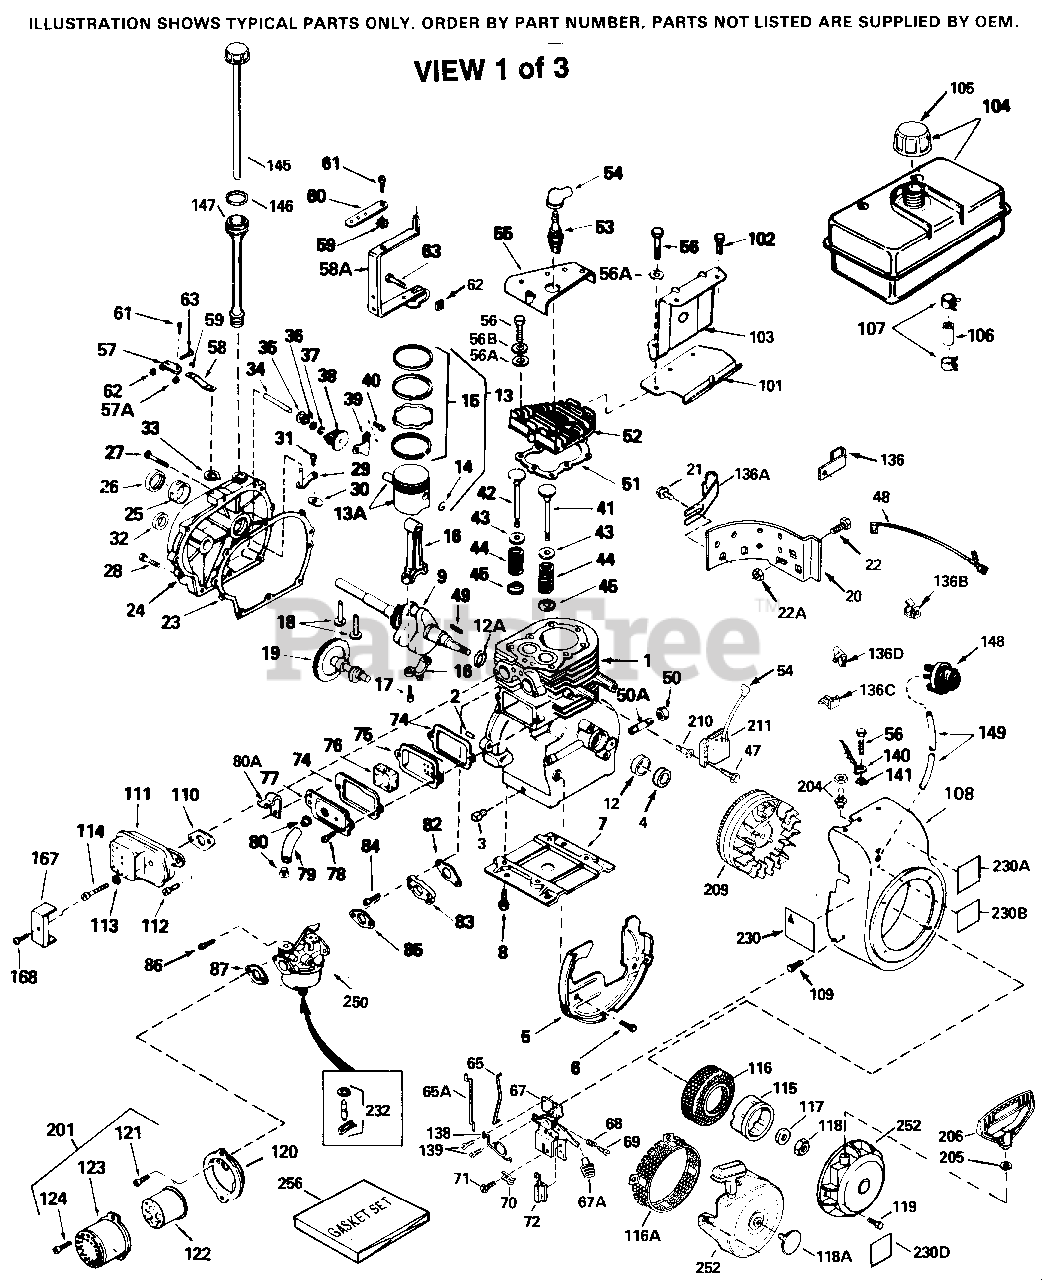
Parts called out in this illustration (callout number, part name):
1	"Cylinder (Incl. 2, 20 & 72)
2	Dowel Pin
15	Governor Rod (Incl. 15A & 15B)
15A	Governor Yoke
15B	Screw, 6-40 x 5/16"
16	Governor Lever
17	Governor Lever Clamp
18	Screw, 8-32 x 5/16"
19	Speed Control Spring
20	Oil Seal
23	Ball Bearing
25	Blower Housing Baffle
26	Screw, 1/4-20 x 5/8"
28	Lock Nut, 8-32
30	Crankshaft
35	Screw, 10-32 x 3/4"
36	Lock Washer #8
37	Lock Nut, 10-32
38	Retaining Ring
40	Piston, Pin & Ring Set (Std.)
40	Piston, Pin & Ring Set (.010" OS)
40	Piston, Pin & Ring Set (.020" OS)
41	Piston & Pin Ass'y. (Std.) (Incl. 43)
41	Piston & Pin Ass'y. (.010" OS) Incl. 43
41	Piston & Pin Ass'y. (.020" OS) Incl. 43
42	Ring Set (Std.)
42	Ring Set (.010" OS)
42	Ring Set (.020" OS)
43	Piston Pin Retaining Ring
45	Connecting Rod Ass'y. (Incl. 46)
48	Valve Lifter
50	Camshaft (BCR)
60	Blower Housing Extension
62	Screw, 8-32 x 3/8
65	Screw, 10-24 x 1/2"
69	* Cylinder Cover Gasket
70	Cylinder Cover Incl. 74,75,80,175 & 1 76
72	Oil Drain Plug (Sq. hd., 1/4-18)
74	Bearing Retainer
75	Oil Seal
80	Governor Shaft
82	Governor Gear Ass'y. (Incl. 81)
83	Governor Spool
84	Retaining Ring
86	Screw, 1/4-20 x 1-1/4"
87	Screw, 1/4-20 x 1-3/4"
101	Spark Plug Cover
102	Solid State Mounting Stud
103	Screw, Torx T-15, 10-24 x 1"
110	Ground Wire
119	* Cylinder Head Gasket
120	Cylinder Head (Incl. 3 of 130)
125	Exhaust Valve (Std.)(Incl. 151)
125	Exhaust Valve (1/32" OS) (Incl. 151)
126	Intake Valve (Std.) (Incl. 151)
126	Intake Valve (1/32" OS) (Incl. 151)
139	Governor Gear Bracket
140	Screw, 10-24 x 1/2"
149	Valve Spring Cap
150	Valve Spring
173A	Breather Tube Grommet
184	* Carburetor To Intake Pipe Gasket
186	Governor Link
200	Control Bracket (Incl. 19, 203 & 204)
203	Compression Spring
204	Screw, 5-40 x 7/16"
206	Terminal
209	Screw, 10-32 x 1/2"
210	Conduit Clip
211	Screw, 10-32 x 3/8"
224	* Intake Pipe Gasket
227	Air Cleaner Elbow (Machined)
228	Stud, 1/4-20 x 6.20"
229	Nut & Lock Washer, 1/4-20
232	Pop Rivet (Purchase Locally)
235	Air Cleaner Elbow Fitting
238	Screw, 10-32 x 7/8"
239	* Air Cleaner Gasket
239A	* Air Cleaner Gasket
245A	Air Filter
250	Air Cleaner Cover
260	Blower Housing
262	Screw, T-40, 5/16-24 x 21/32"
265	Cylinder Head Cover
272	Screw, 5/16-18 x 3/4"
273	Carburetor Flange
275	Muffler
285	Starter Cup
286	Starter Screen
287	Screw, 1/4-28 x 7/16"
291	Fuel Line
292	Fuel Line Clamp
298	Screw, 1/4-15 x 3/4"
299	"U" Type Nut
300	Fuel Tank (Incl. 292 & 301)
301	Fuel Cap (Red)
305	"O" Ring
305	Oil Fill Tube
308	Fill Tube Clip
310	Oil Fill Plug
325	Wire Clip
340	Fuel Tank Bracket
341	Fuel Tank Bracket
342	Screw, 1/4-20 x 5/8"
366	Muffler Elbow
366A	Muffler Nipple
367	Lock Nut
370	Instruction Decal
370A	Logo Decal
370B	Instruction Decal
380	Carburetor (Incl. 184)
390	Rewind Starter
400	* Gasket Set (Incl. items marked PK in notes) Incl. part #'s 27272 (2), 2789 6 (2), 27913 (1), 27915 (2), 27930 (1 ), 28938B (1), 29673 (1), 30684 (1), 31688 (1), 33355 (1)
420	SAE 30 4-Cycle Engine Oil (Quart)
453	Engine Mounting Base
454	Screw, 5/16-18 x 3/4"
